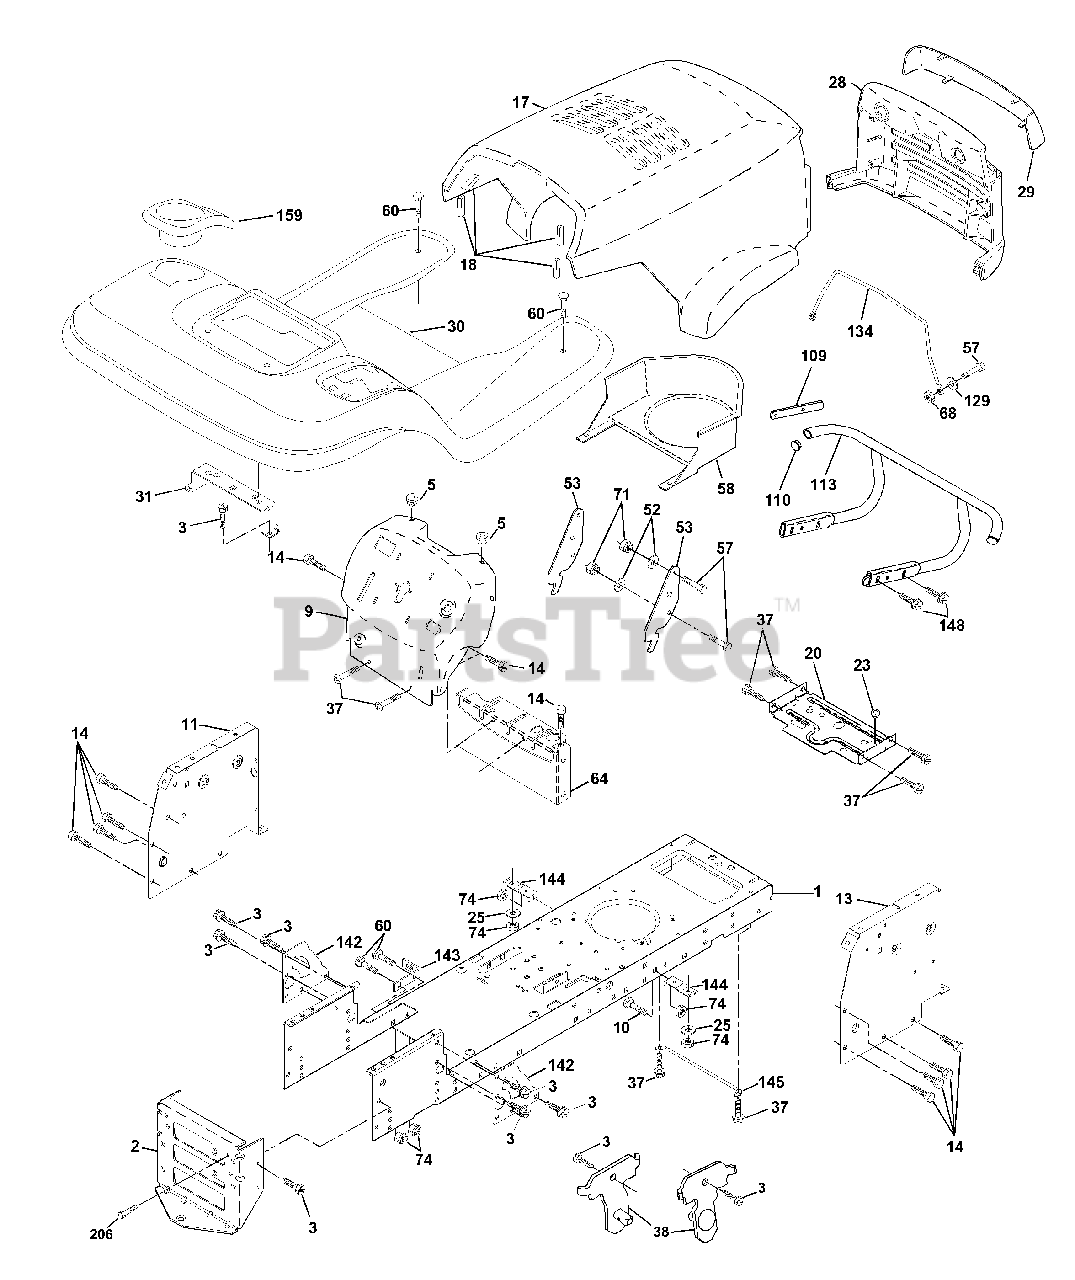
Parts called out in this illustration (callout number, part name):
2	Drawbar,
3	Screw 3/8-16x3/4
5	Bumper Hood/Dash
9	Dash Slkscr
10	Bolt Carriage 3/8-16 x 1
11	Panel Dash Lh
13	Panel Dash Rh
14	Screw Thdrol 3/8-16x1/2 Ty-tt
17	Hood LT/PL Husqvarna
18	Bumper, Hood
20	Plate Mtg Battery Fuel Tank Fr
25	Washer 13/32 X 13/16 X 12 Ga
26	Nut Lock Hex W/Ins 3/8-16 Unc
28	Grille LT/PL Husqvarna
29	Lens LT/PL Husqvarna
30	Fender Footrest STLT Pnt
31	Bracket Support Fender
37	Screw Thdrol 6/16-18 x 1/2 TYT
38	Bracket Asm Pivot Mower Rear
52	Washer 9/32 x 7/8 x 16 Ga.
53	Bracket Pnt. Pick off LT/PL Husqvarna
57	Bolt Hex 1/4-20 x 3/4
58	Air Duct Engine CV18
60	Bolt Rdhd Sqnk 3/8-16unc x 3/4
64	Dash Lower STLT
68	Nut Keps Hex 1/4-20 Unc
71	Nut Crownlock 1/4-20 Unc
74	Nut Crownlock 3/8-16 UNC
109	Bracket Extension Bumper
110	Plug Plastic
113	Bumper Asm.
129	Washer 9/32 x 5/8 x 16 Ga.
134	Rod Support Hood LT/PL Husq.
142	Plate Reinforcement STLT
143	Bracket Swaybar Chassis
144	Bracket Pnt Footrest STLT
145	Rod Pivot Chassis/Hood
148	Screw 3/8-16 x 1-1/4
159	Cup Holder STLT Grey
206	Bolt Shoulder 5/16-18 TT
